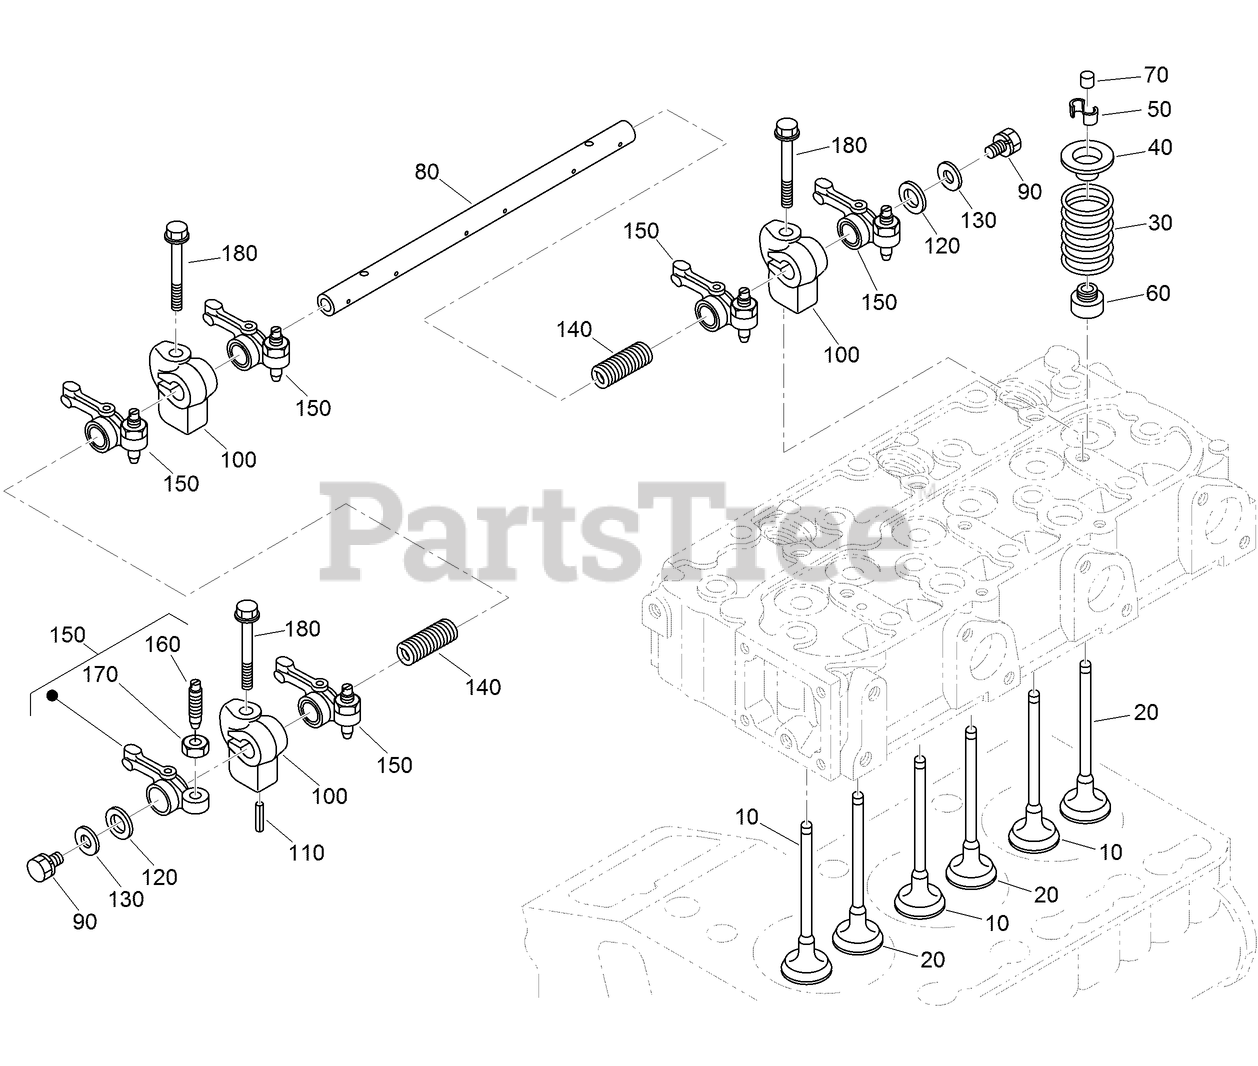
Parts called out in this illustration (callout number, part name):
10	VALVE-INLET
20	VALVE-EXHAUST
30	SPRING-VALVE
40	RETAINER-SPRING
60	SEAL-STEM, VALVE
70	CAP-VALVE
80	SHAFT-ARM, ROCKER
90	BOLT-FLANGE
100	BRACKET-ARM, ROCKER
110	PIN-SPRING
120	WASHER-SHAFT, ROCKER ARM
130	WASHER-PLAIN
140	SPRING-ARM, ROCKER
150	ROCKER ARM ASM
160	SCREW-ADJUSTING
